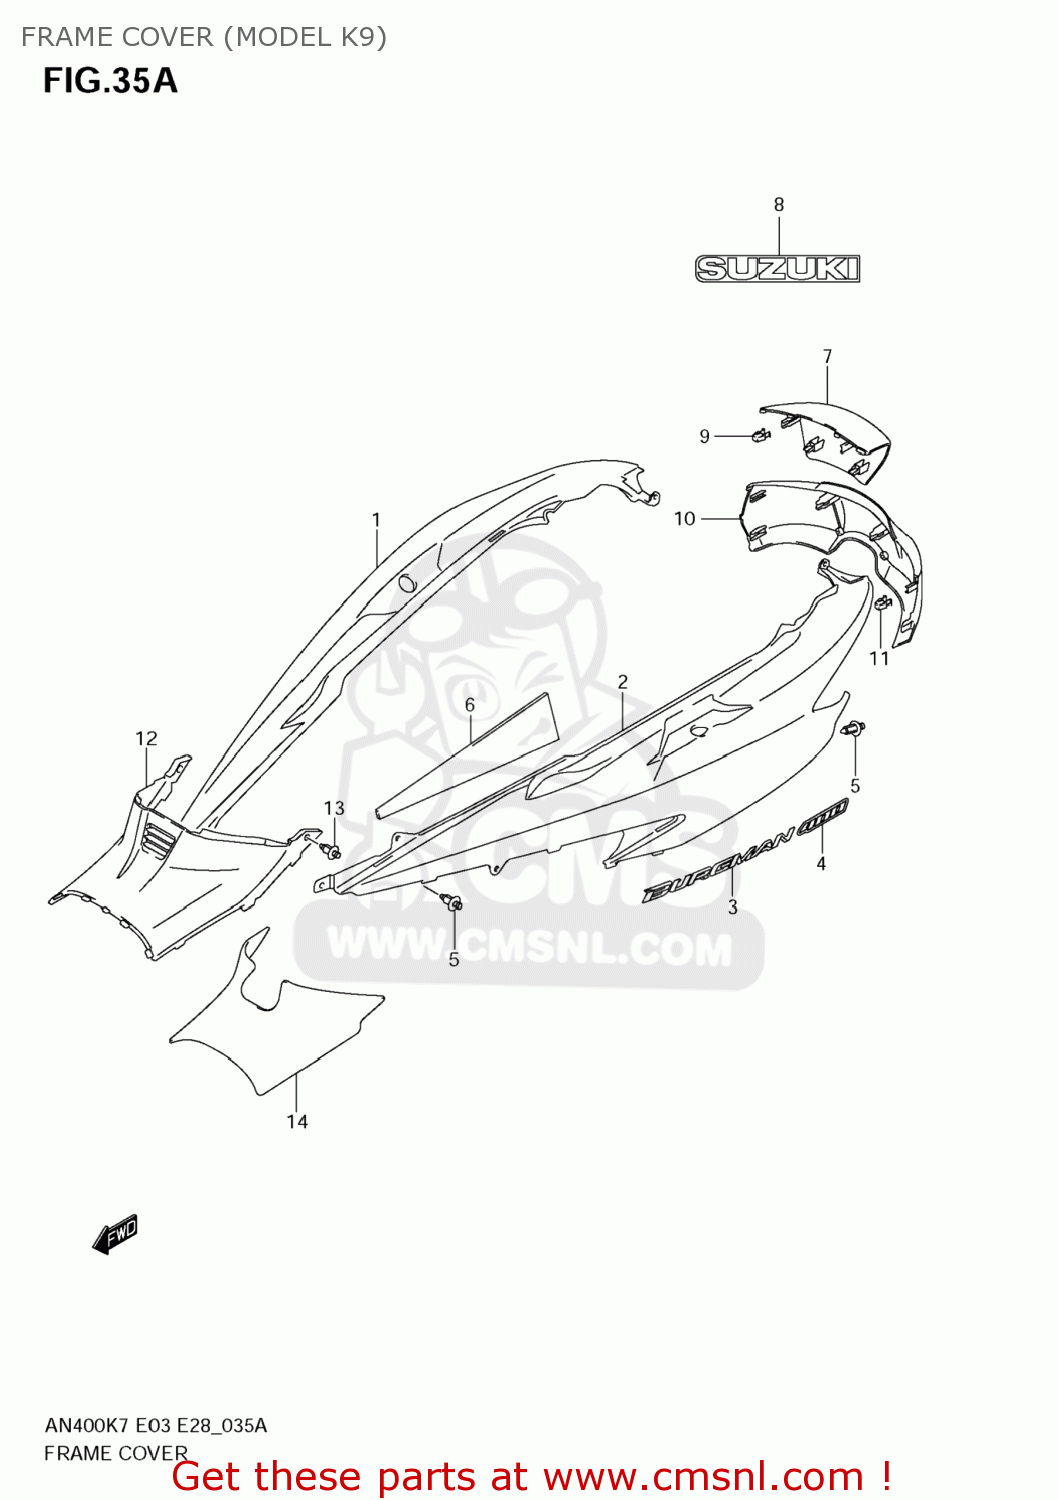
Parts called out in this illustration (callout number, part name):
1	COVER,FRAME,R(RED)
2	COVER,FRAME,L(RED)
3	EMBLEM,FRAME COVER
4	EMBLEM,400
5	CLIP(BLACK)
6	CUSHION,FRAME COVER
7	COVER,FRAME CTR
8	EMBLEM,SUZUKI(GRAY)
9	CLIP
10	COVER,FRAME LWR
11	CLIP(BLACK)
12	COVER,FRAME FR
13	CLIP(BLACK)
14	CUSHION,FRAME COVER FR
